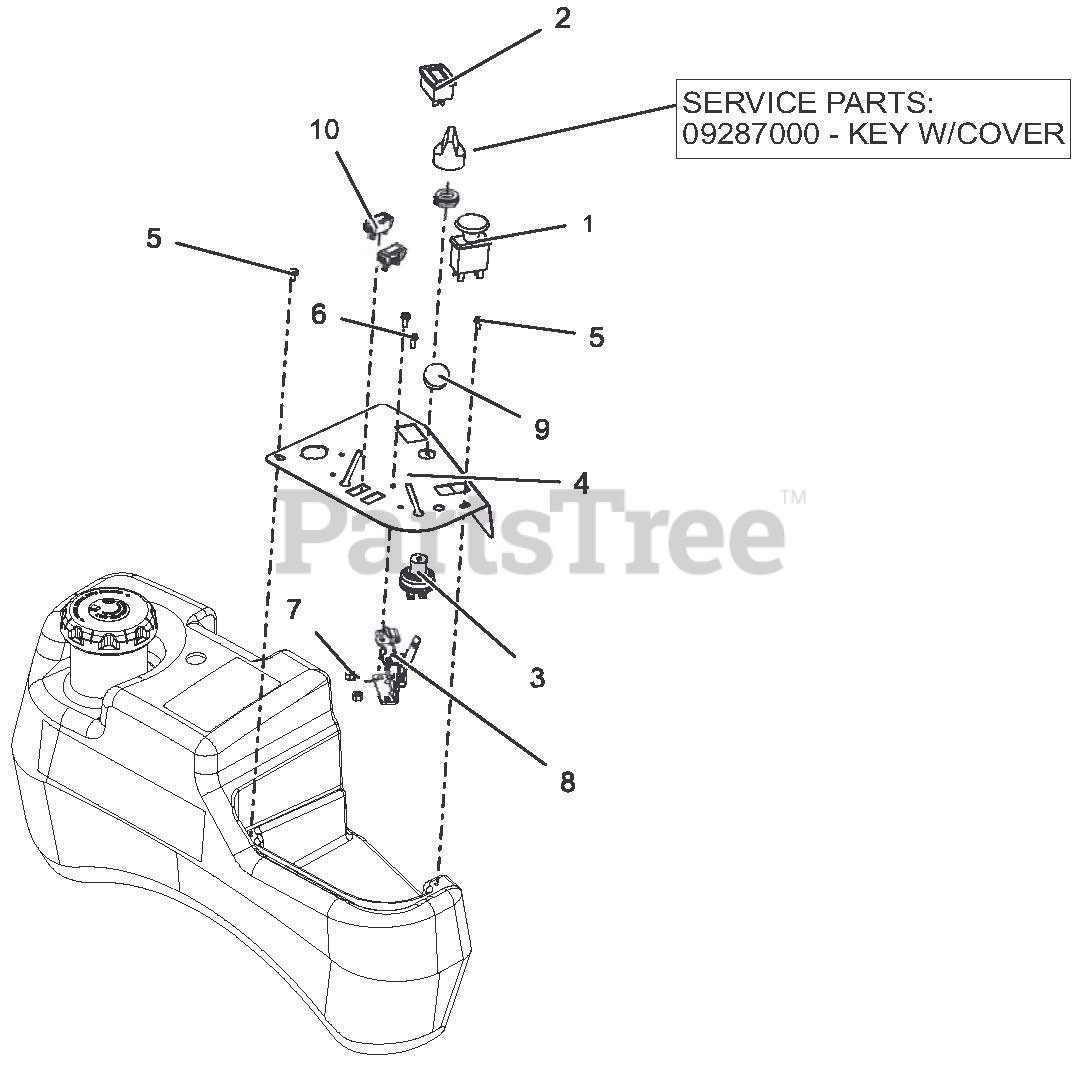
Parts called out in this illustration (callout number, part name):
1	SWITCH, CLUTCH
2	METER, HOUR W/MAINTENANCE
3	SWITCH, IGNITION
4	PANEL, CONTROL - PROTURN 100
5	SCR-MCH 10-24X.38 HWHSTAINLESS
6	@SCR-MCH 10-24X.50 HWH YWZC
7	NUT-LK-NYL #10-24 YWZC
8	CABLE, PRO-CONTROL THROTTLE
9	KNOB, CONTROL BLACK .38-16X.50
10	LIGHT, INDICATOR
11	KEY W/COVER
